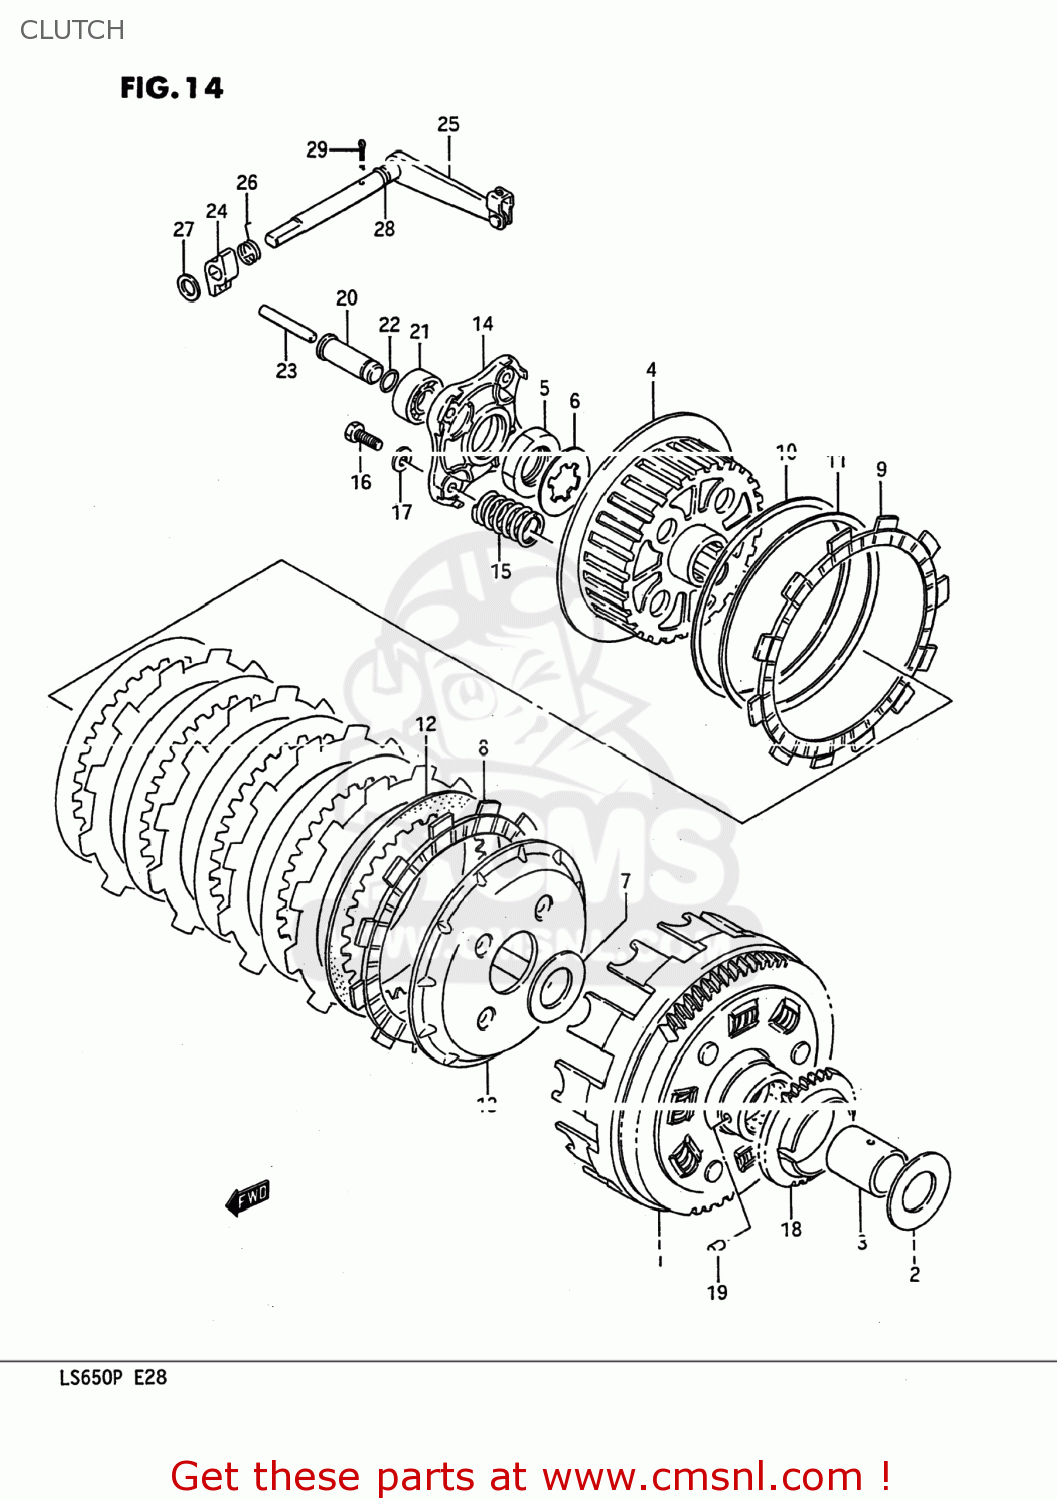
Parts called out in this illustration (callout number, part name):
1	GEAR ASSEMBLY,PRIMARY DRIVE
2	WASHER
3	SPACER(22X28X32.5)
4	HUB,CLUTCH SLEEVE
5	NUT
6	WASHER,LOCK
7	WASHER
8	PLATE,CLUTCH DRIVE (NAS)
9	PLATE,CLUTCH DRIVE(T:3.5) (NAS)
10	SEAT,WAVE WASHER(T:1.4)
11	WASHER
12	PLATE,CLUTCH DRIVEN(T:1.6) (NAS)
13	DISC,CLUTCH PRESSURE
14	PLATE,RELEASE
15	SPRING
16	BOLT
17	WASHER
18	GEAR,ENG OIL PUMP DRIVE
19	PIN(6X6)
20	PIECE,CLUTCH PUSH
21	BEARING
22	O RING(D:1.9,ID:8.6)
23	ROD,CLUTCH PUSH
24	CAM,CLUTCH RELEASE
25	ARM ASSY,CLUTCH RELEASE
26	SPRING
27	WASHER,THRUST
28	O RING(D:1.9,ID:6.8)
29	PIN 20X20
